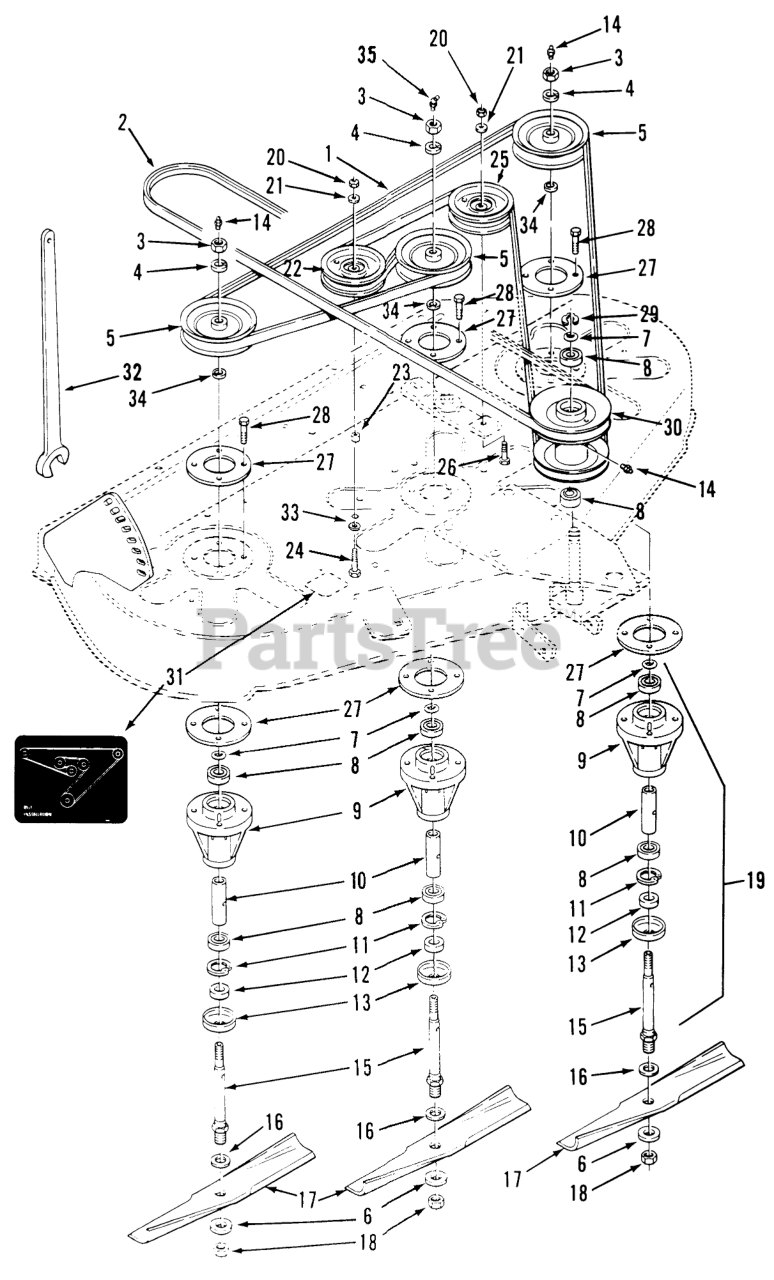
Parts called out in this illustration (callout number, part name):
1	V-BELT
2	V-BELT
3	Nut
4	Lockwasher
5	Pulley
6	Washer
7	O RING
8	BEARING-BALL
9	HOUSING-SPINDLE
11	Ring-Snap
12	SPACER-BLADE
13	CUP-SPINDLE
14	Fitting-Grease
15	SHAFT-SPINDLE
16	Washer
17	SERV ASS'Y-BLADE PKG
18	Nut
19	Spindle Assembly
20	NUT
21	Washer
22	Pulley-Idler
23	SPACER
24	Bolt
25	PULLEY-FLAT IDLER
26	BOLT
27	SPACER-SPINDLE
28	Bolt
29	RETAINING RING
30	PULLEY-COUNTER SHAFT
31	DECAL-BELT INSTALL
32	Spindle Wrench
33	WASHER
34	Washer
35	FITTING-GREASE
